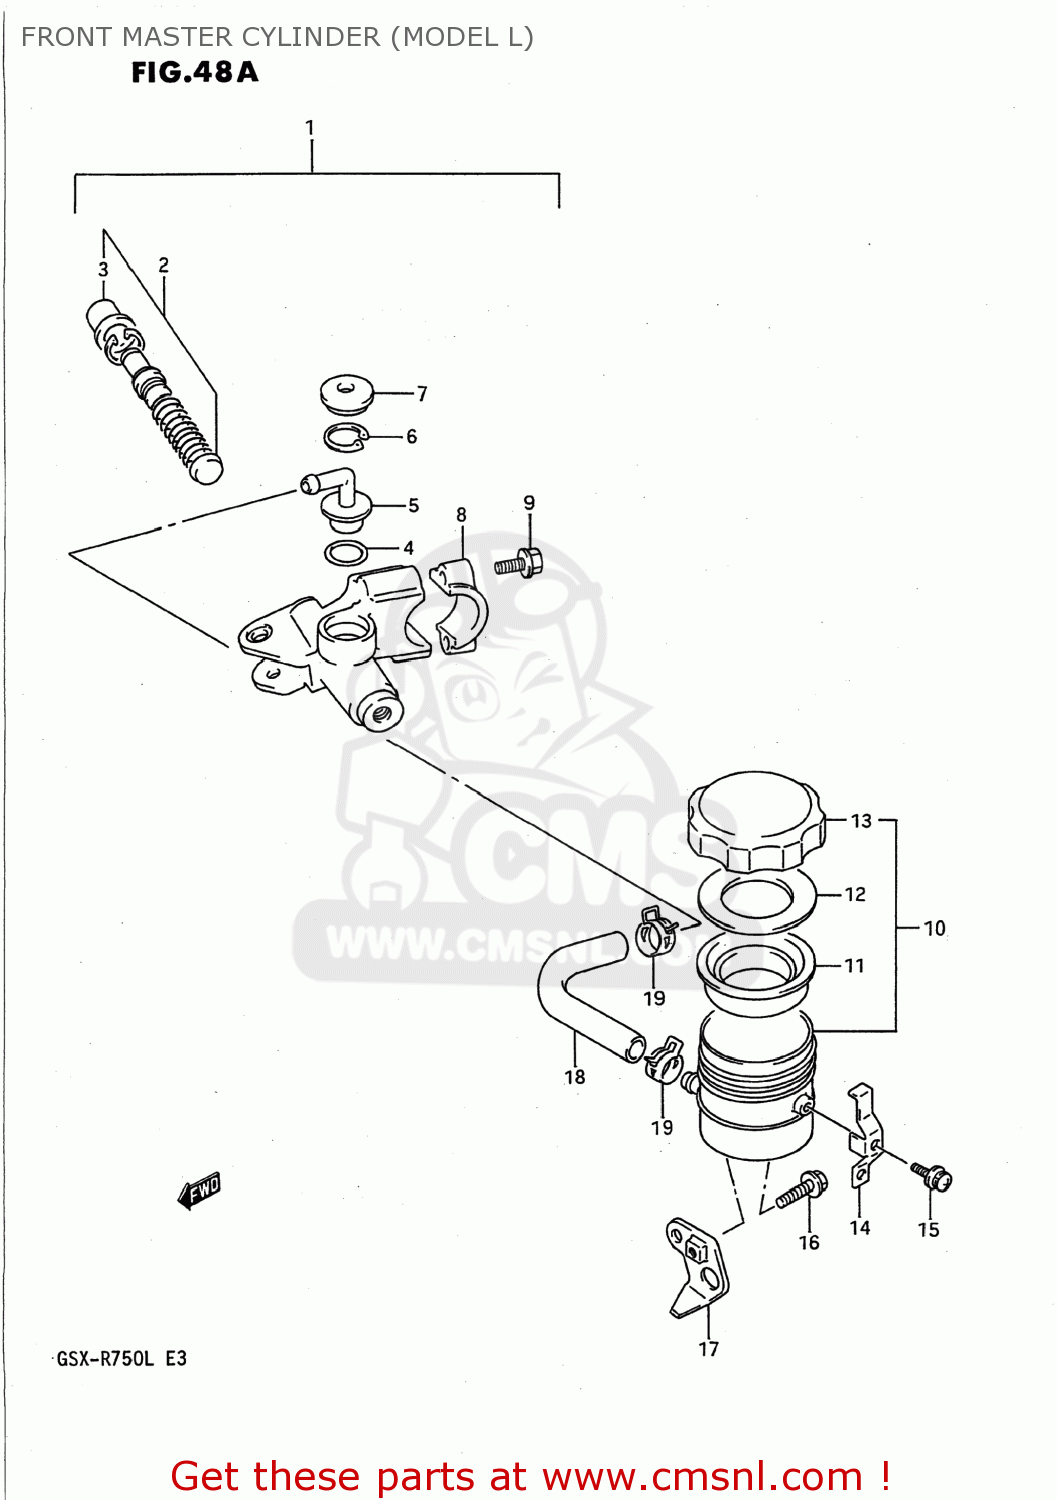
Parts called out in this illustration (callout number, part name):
1	CYLINDER ASSEMBLY,FRONT MASTER
2	PISTON & CUP SET
3	BOOT
4	O RING
5	CONNECTOR
6	CIRCLIP
7	COVER,DUST
8	HOLDER
9	BOLT
10	TANK ASSY,RESERVOIR
11	DIAPHRAGM
12	PLATE,DIAPHRAGM
13	CAP
14	PLATE,RESERVOIR TANK CAP
15	SCREW
16	BOLT 6X16
17	BRACKET COMP,RESERVOIR
18	HOSE,RESERVOIR TANK FR
19	CLAMP,RESERVOIR TANK FR
